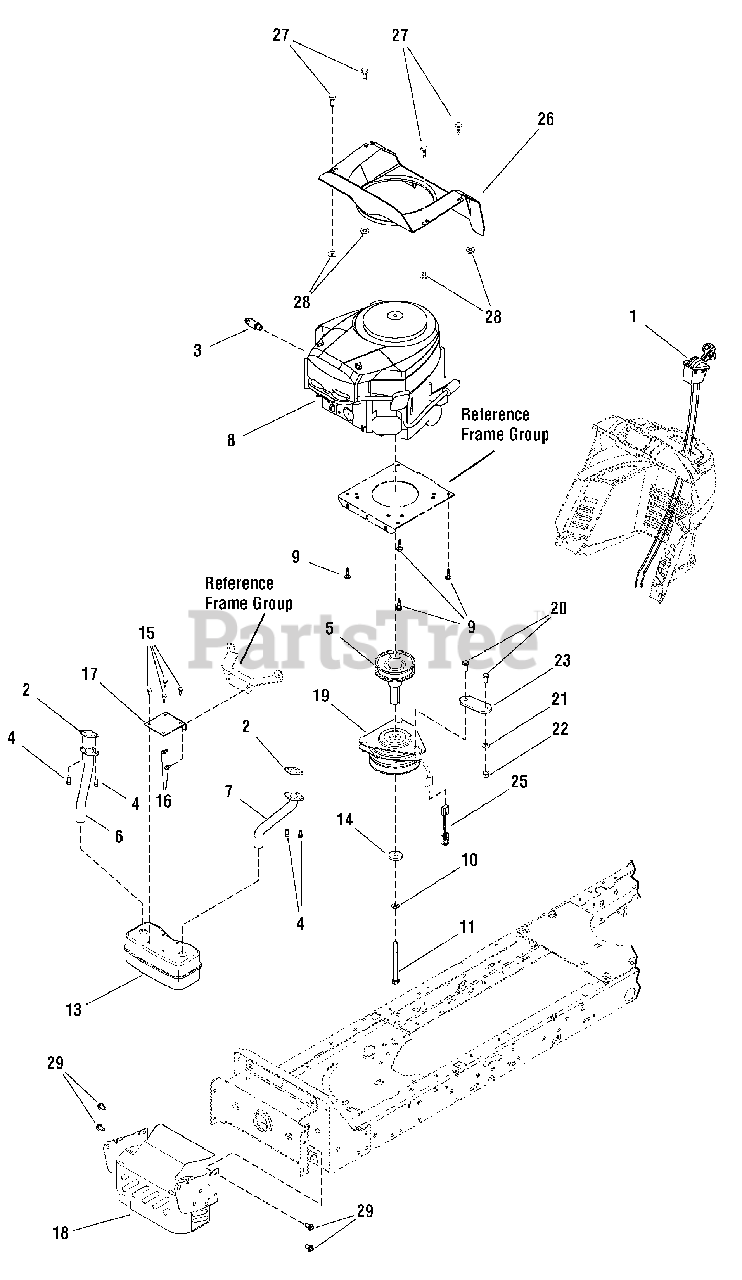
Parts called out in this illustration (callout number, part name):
1	CONTROL, Throttle Double
1	CONTROL, Throttle, Choke-A-Matic
2	GASKET, Exhaust
3	OIL VALVE
4	CAPSCREW, 5/16-18 x 3/4
5	PULLEY, Adapter
6	TUBE, Exhaust, Right
7	TUBE, Exhaust, Left
8	* ENGINE, 23HP Briggs & Stratton
9	SCREW, Self Tap, 3/8-16 x 1-1/4
10	WASHER, Lock, 3/4
11	CAPSCREW, Hex Head, 7/16-20 x 5
13	MUFFLER, Twin
14	WASHER, Flat, 1-1/4
15	SCREW, 1/4-14 X 3/8
16	SCREW, Hex, 1/4-20 x 5/8
17	BRACKET, Muffler
18	HEAT SHIELD ASSEMBLY
19	CLUTCH, Electric, Ogura Adjustable (5.4" Pulley)
20	CAPSCREW, Hex Head, 5/16-18 x 3/4
21	WASHER, Flat, 3/4
22	NUT, Hex Flange, 5/16-18
23	PAD, Anchor Clutch
25	HARNESS, Jumper (to Ogura Clutch)
26	AIR DUCT, Plenum
27	SCREW, Hex Flange, 1/4-20 x 5/8
28	NUT, Hex Flange, 1/4-20
29	CAPSCREW, Hex Head, 5/16-18 x 3/4
